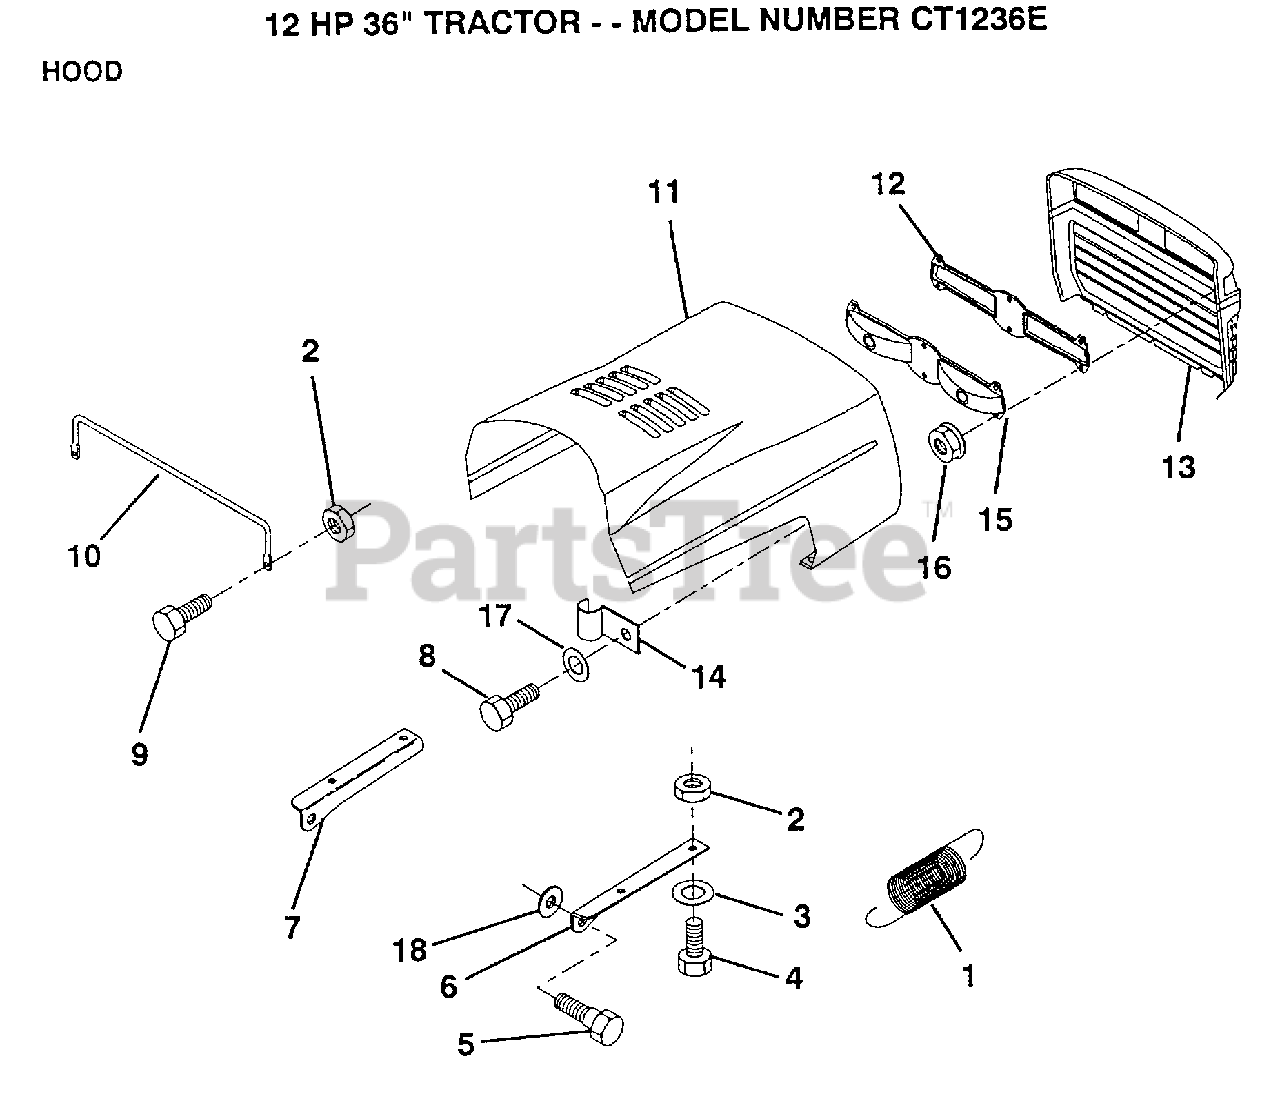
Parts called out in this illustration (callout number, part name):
1	EXT SPRING
2	NUT
3	WASHER
4	BOLT
6	BRKT HOOD RH
7	BRKT HOOD LH
10	"BRACE,HOOD"
11	HOOD
14	CLIP T
16	NUT
17	WASHER
18	WASHER
